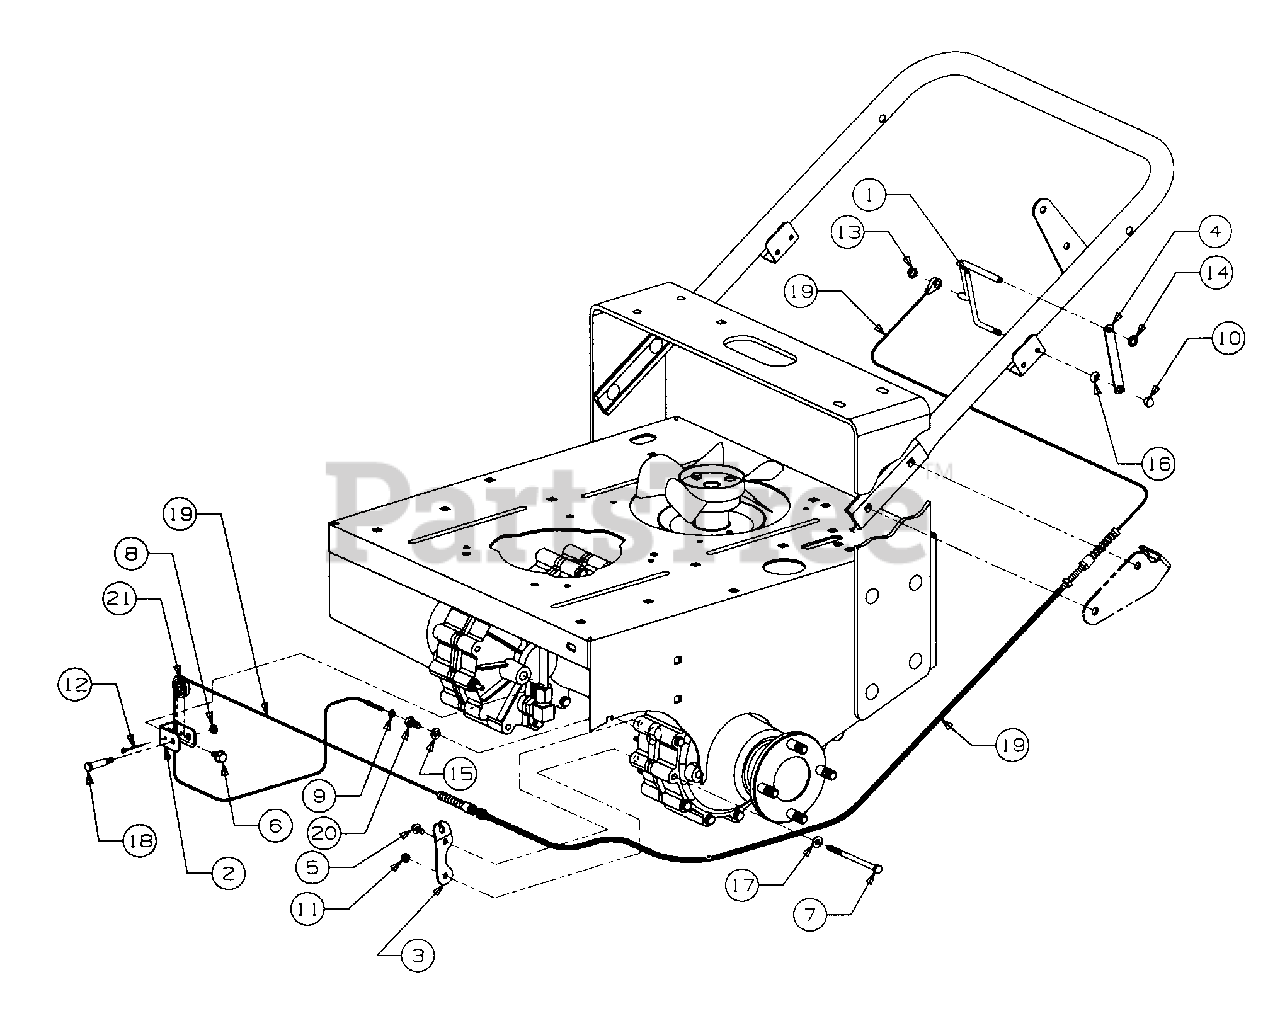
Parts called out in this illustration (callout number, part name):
1	Lever, Drive Wheel Release
2	Bracket, Pulley Mtg
3	Plate, Release Cable Mtg
4	Plate, Retainer
5	Screw, Hex Wash Hd Tapp, 1/4-20 X .50 Lg
6	Screw, Hex Wash SF-Tapp, 5/16-24 X .50 Lg
7	Screw, Hex Cap, 1/4-20 X 4.0 Lg
8	Nut, Hex Top Lock, 1/4-20
9	Nut, Hex, #10-32
10	Nut, Hex Lock Stop, 1/4-28
11	Nut, Hex Top Lock, 1/4-20 GR5
12	Pin, Cotter, 5/32 Dia X 1.25 Lg
13	Nut, Cap Speed, .312 Stud
14	Nut, Push-On Speed, 5/16
15	Washer, Lock, 5/16
16	Washer, Spring
17	Washer, Flat, .25 X .62
18	Bolt, Pulley
19	Cable, Drive Wheel Release
20	Bolt, Cable Adapter
21	Pulley, Cable
